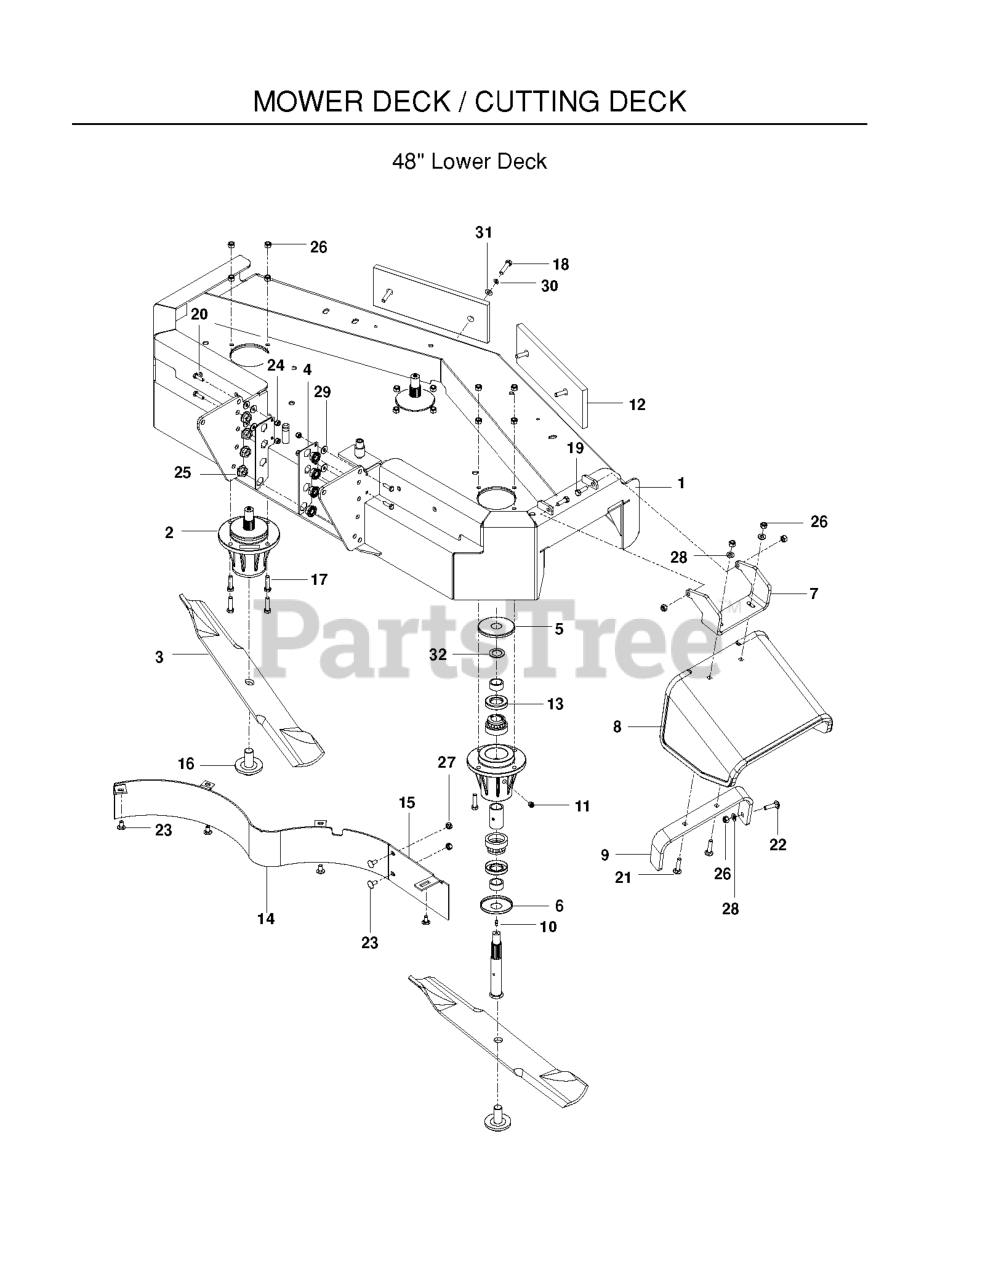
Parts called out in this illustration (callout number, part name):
1	DECK SVC W/DECALS WH4818
2	HOUSING ASM, 72
3	BLADE OEM 16 1/4"
4	PLATE NUT - PAINTED
5	TOP DUST CAP
6	BOTTOM DUST CAP
7	HINGE CHUTE - BLACK
8	CHUTE, RUBBER DISCHARGE WB
9	BRKT, REINF-CHUTE WB
11	PLUG-VENTED
12	WEIGHT, COUNTER, ORANGE
13	SHAFT SEAL
14	BAFFLE WLDT, BLACK
15	CENTER BAFFLE 48"
16	BLADE BOLT/WASHER
17	HCS 5/16C X 1 1/4
18	HCS 1/2-13 X 1-1/2 GR 5 ZD
19	HCS 5/16C X 1
20	HCS 1/4-20X7/8 GR5
21	RHSNB 5/16-18 X 1-1/2 GR 5 ZD
22	BOLT, CARRIAGE 5/16X1-1/4
23	CARRIAGE BOLT 5/16C X 5/8"
24	NUT.1/4-20.HEX.NYLOC.ZD
25	NUT FLANGE 1/2-13 GR 5
26	NUT 5/16 NYLOC
27	5/16-18 NYLOC FLANGE NUT
28	FLAT WASHER 5/16 SAE
29	WASHER 1/4 FLAT
30	WASHER 1/2" SPLIT LOCK
31	WASHER 1/2" FLAT
32	MACHINE BUSHING
